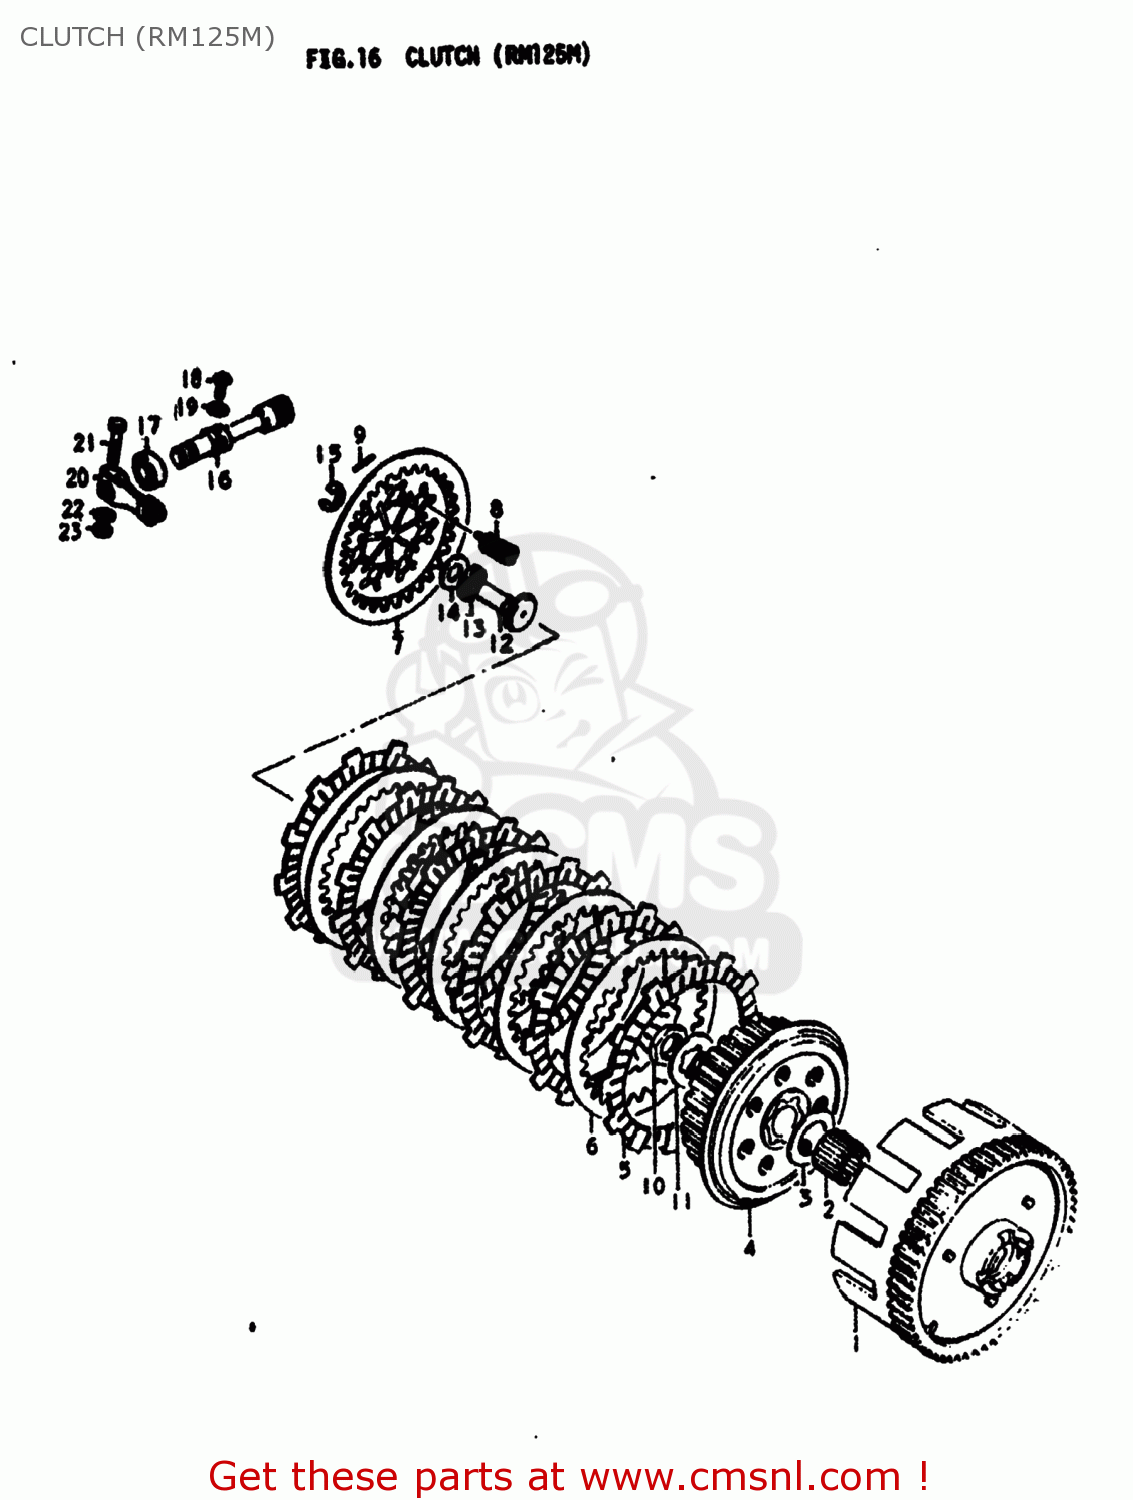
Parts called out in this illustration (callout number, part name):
1	GEAR ASSEMBLY,PRIMARY DRIVE
2	BEARING
3	WASHER
4	HUB,CLUTCH SLEEVE
5	PLATE,CLUTCH DRIVE
6	PLATE,CLUTCH DRIVEN (NAS)
7	PLATE,CLUTCH PRESSURE
8	SPRING
9	PIN(2.5X19.8)
10	NUT
11	WASHER,LOCK
12	RACK,CLUTCH RELEASE
13	BEARING(10X22X2.8)
14	WASHER
15	E RING 8MM
16	PINION,CLUTCH RELEASE
17	OIL SEAL
18	BOLT(6X12)
19	WASHER
20	ARM,CLUTCH RELEASE
21	BOLT
22	WASHER
23	NUT
